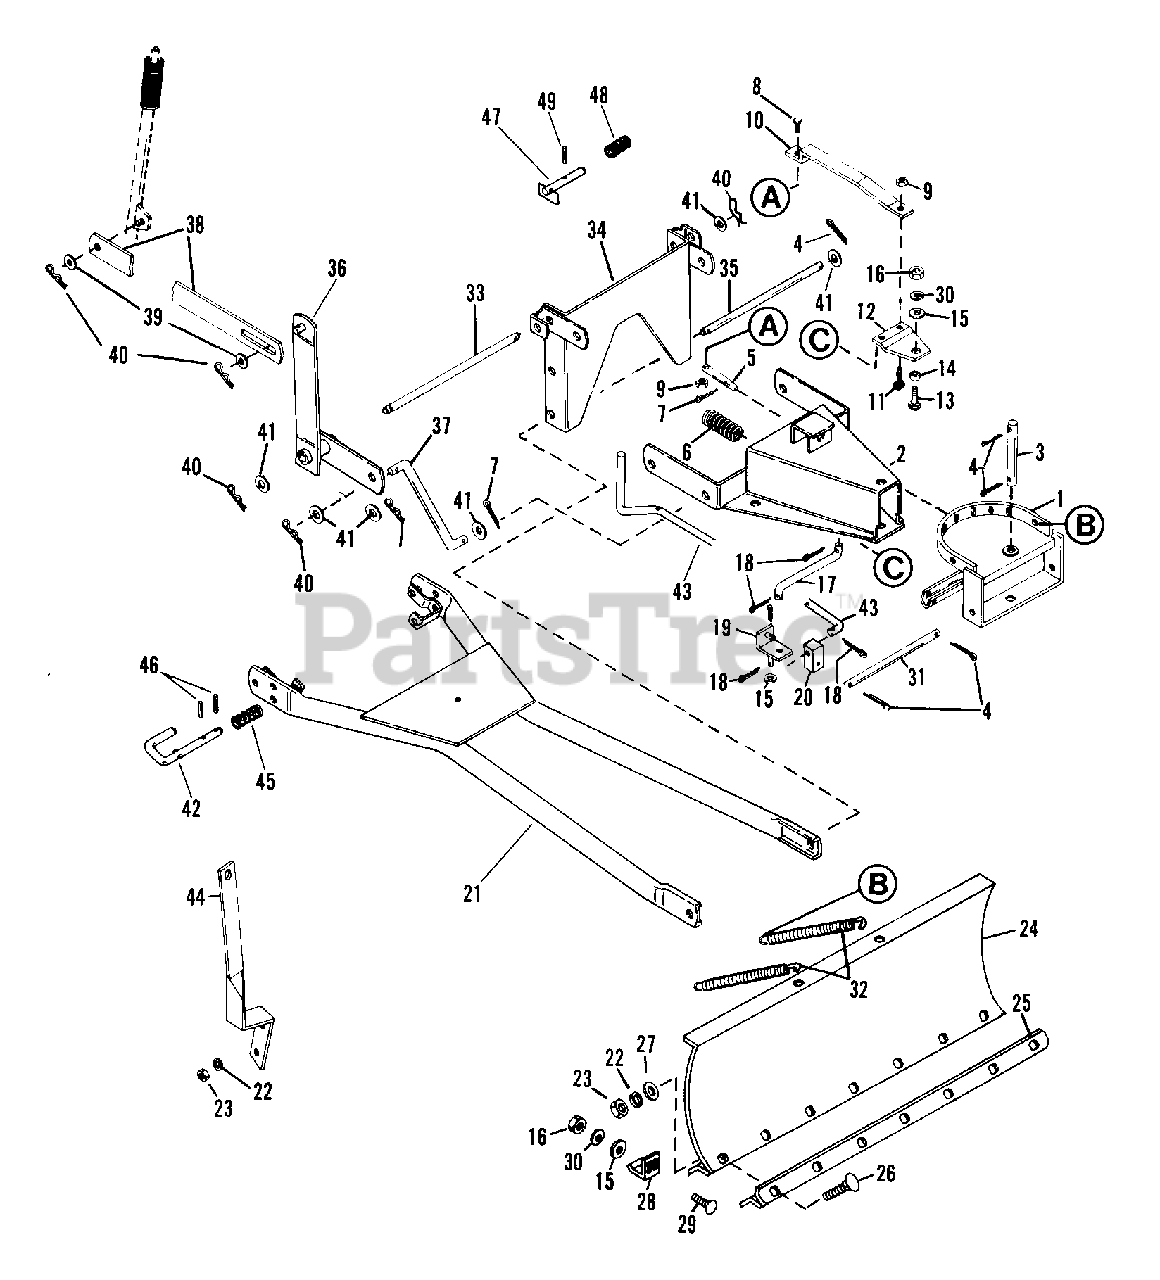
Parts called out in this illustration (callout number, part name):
1	SUPPORT
2	PUSH FRAME
4	PIN-COTR .18X1.0 PL
5	LATCH PIN
6	SG-COMP .080X.85X1.44
7	PIN-COTR .12X1.0 PL
8	BLT-HEX .31-18X1.25 PL GR2
9	NUT-LK .312-18 GR A PL
11	BLT-RDHDSQNK .312-18X.62SHTPL
12	PIVOT PLATE
13	BLT-HEX .38-16X1.00 PL
14	SPACER .406X.749X.162
15	WSHR-FL-STL .438X1.0X.083 PL
16	NUT-HEX .375-16
18	PIN-COTR .12X.75 PL
20	UNIVERSAL BLOCK JOINT
21	BLADE CARRIAGE
22	WSHR-LK .312X.097 PL HVY
23	NUT-HEX .312-18
24	WELDMENT, SNOW BLADE
25	WEAR PLATE
26	BLT-RDHDSQNK .31-18X1.00 PL
27	WSHR-FL-STL .38X.875X.083 PL
28	SKID SHOE
29	BLT-RDHDSQNK .38-16X1.0 PL
30	WSHR-LK .375X.094 MED PL
32	SG-TENS .187X1.50X9.94 WLD 40
33	MOUNT ROD
34	PIVOT FRAME
35	PIVOT ROD
36	LIFT BELLCRANK
37	LIFT LINK
38	LIFT STRAP
39	WSHR-FL-STL .531X1.062X.095 PL
40	PIN-HAIR INT .09X.188 PL
41	WSHR-FL-STL.656X1.312X.095 PL
42	LATCH PIN
43	CONTROL ROD
44	CONTROL SUPPORT
45	SPRG, COMP .058X.65X2.13 WLD15
46	PIN-ROLL .125X.75
47	HITCH PIN
48	SG-COMP .072X.77X1.75
49	PIN-ROLL .188X1.50
